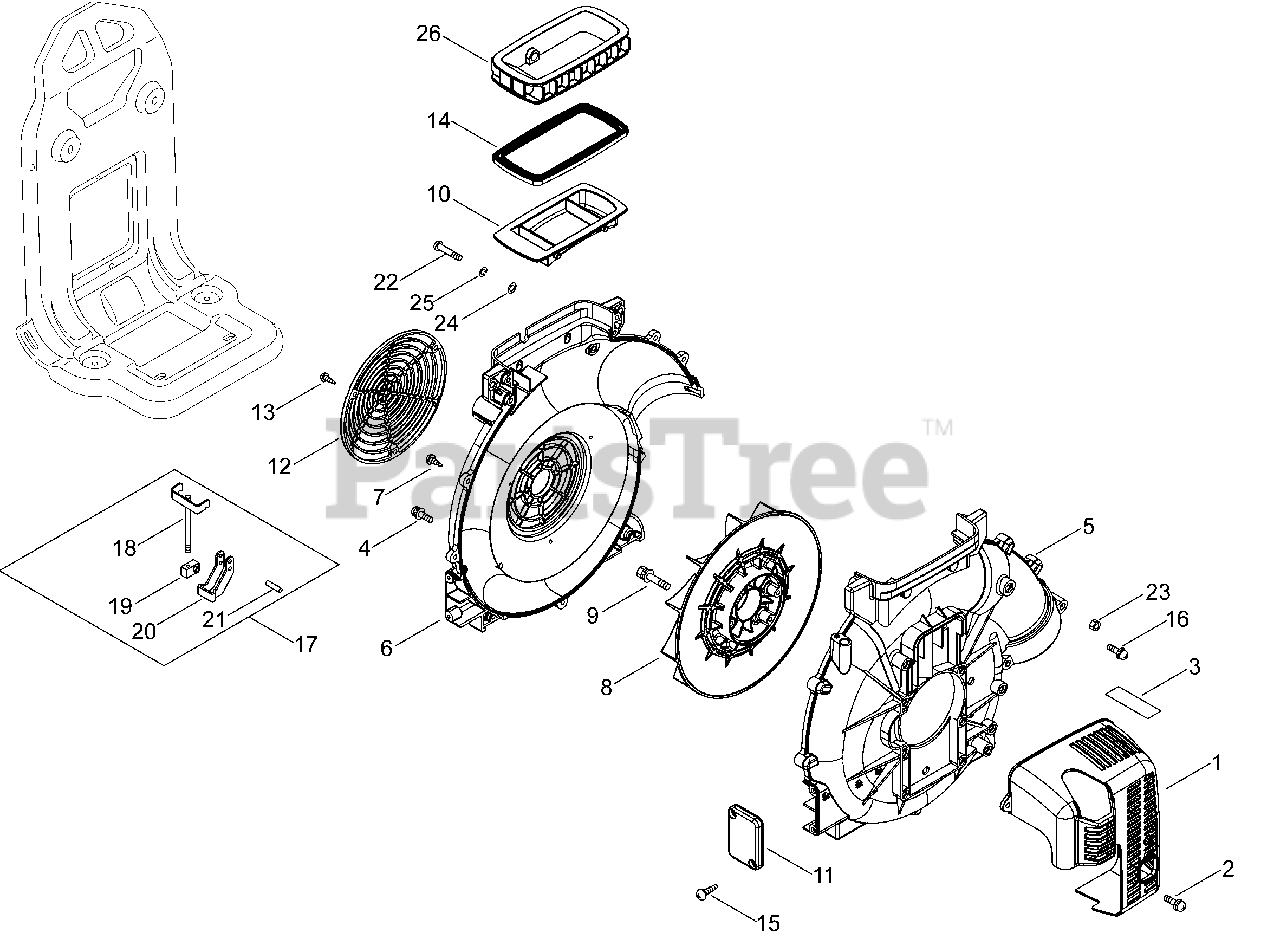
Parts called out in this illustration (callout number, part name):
1	COVER, ENGINE
2	SCREW 5×20
3	LABEL, CAUTION - HOT
4	SCREW 5×14 SUS
5	CASE, FAN
6	COVER, FAN
7	SCREW 5×25 SUS
9	BOLT 5×35
10	HOLDER, TANK - LOWER
11	PLUG, FAN CASE
12	GUARD, DEBRIS
13	SCREW 5×16 SUS
14	GASKET, LOWER TANK
15	SCREW 5×16 SUS
16	SCREW 5×14 SUS
17	RETAINER ASSY, CHEMICAL TANK
19	CONNECTOR, BRACKET
20	RETAINER, CHEMICAL TANK
23	NUT, LOCK M5
24	WASHER SS 5mm
25	WASHER, SPRING 5 SUS
26	TANK, LOWER
